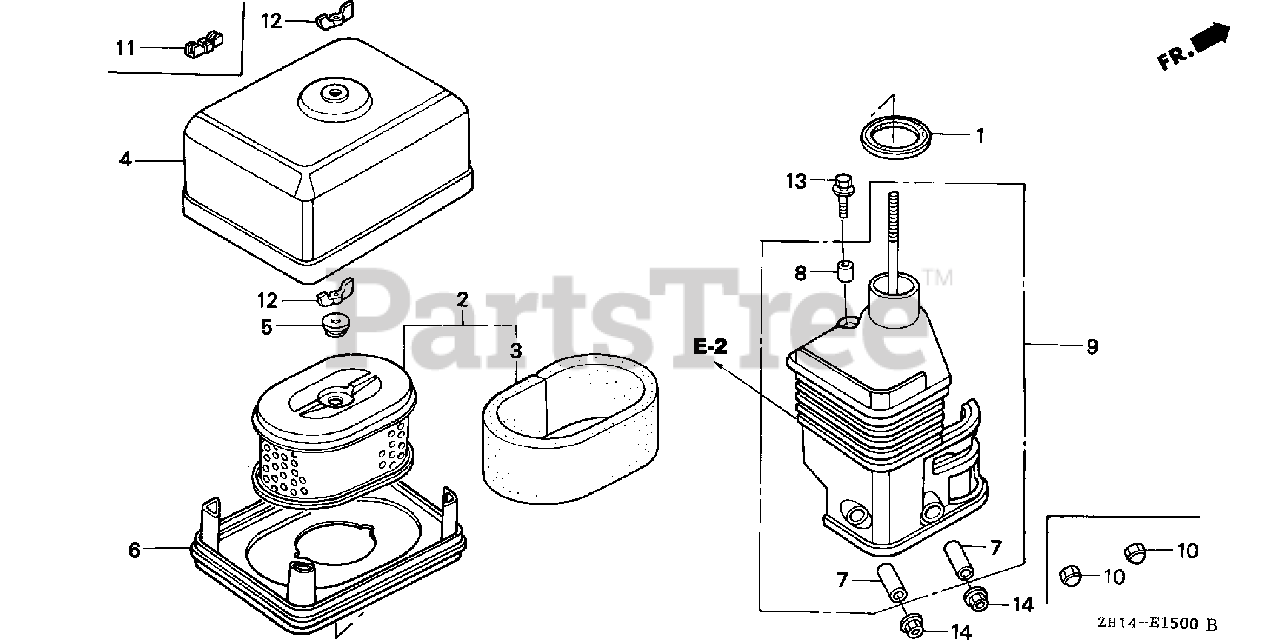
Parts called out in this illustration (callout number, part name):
1	GASKET, ELBOW
2	ELEMENT, AIR CLEANER (DUAL)
3	FILTER (OUTER)
4	COVER, AIR CLEANER (DUAL)
5	GROMMET, AIR CLEANER
6	NOSE, MUFFLER
7	COLLAR, AIR CLEANER
8	COLLAR B, AIR CLEANER
9	ELBOW, AIR CLEANER
12	NUT, TOOL BOX SETTING
13	BOLT, FLANGE (6X20)
14	NUT, FLANGE (6MM)
